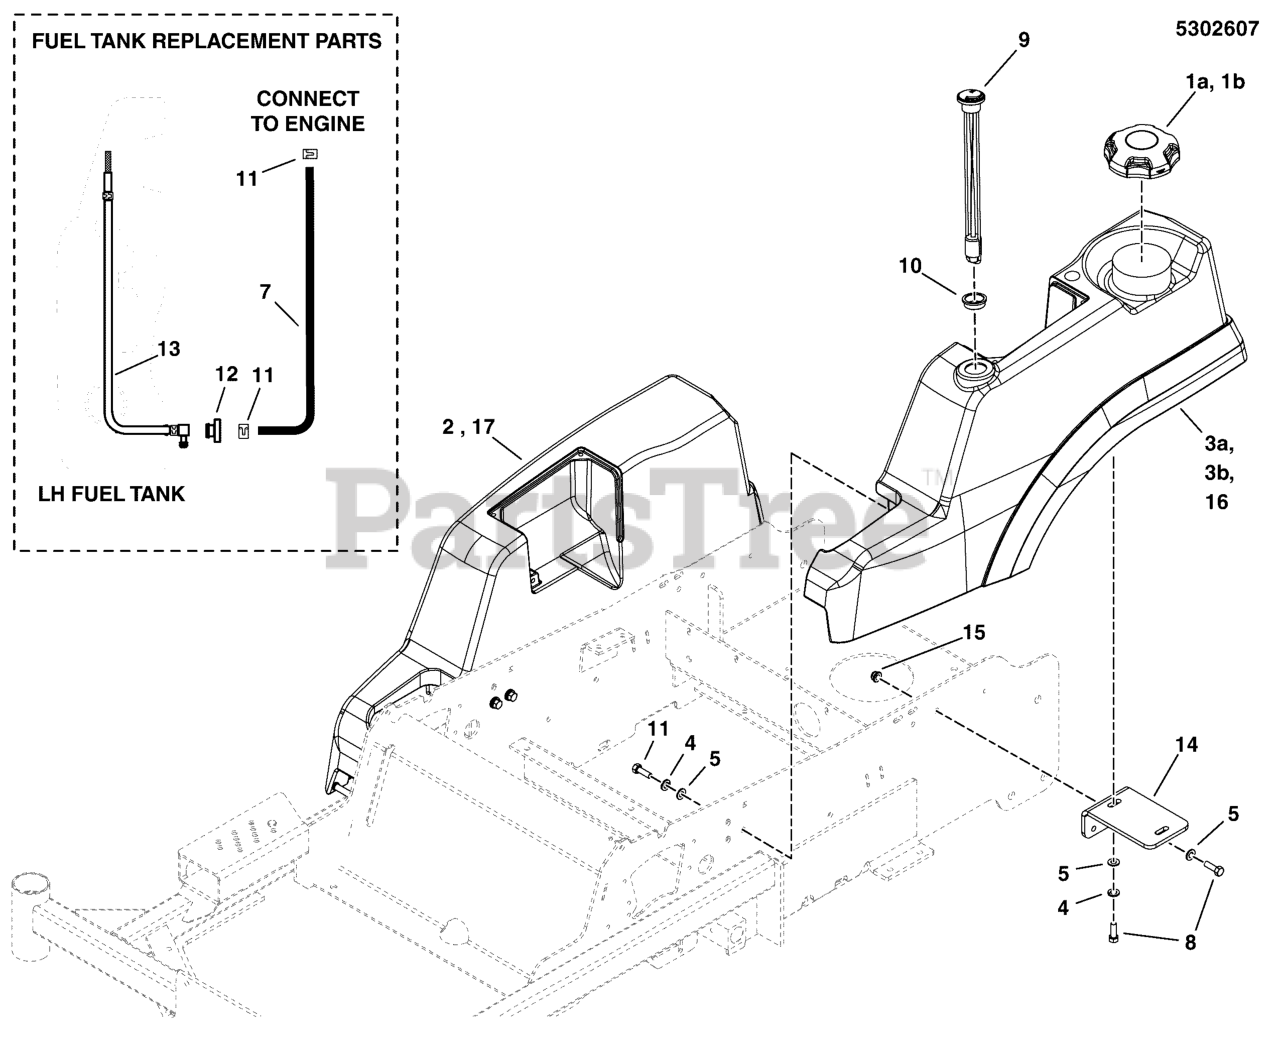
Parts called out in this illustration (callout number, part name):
2	TANK, FENDER, RH
4	WASHER, 5/16 LOCK CZ
5	WASHER, 5/16" SAE
7	HOSE, FUEL, 1/4 IN, LW PRMTN, 24" LONG
8	BOLT, 5/16-18 X 1 GD5 YZ
9	FUEL GAUGE, 10"
10	GROMMET, FUEL GAUGE
11	CLAMP, HOSE, EXTERNAL, 1/2 - RED
12	BUSHING-FUEL TANK RED RUBBER
13	PICKUP TUBE ASSEMBLY, FUEL LINE
14	MOUNT, TANK, REAR - BLK
15	NUT, 5/16-18 HEX NYLOCK FLANGE
16	TANK, FUEL, SNP-PRO, LH, 2013
17	TANK, FENDER, SNP-PRO, RH, 2013
